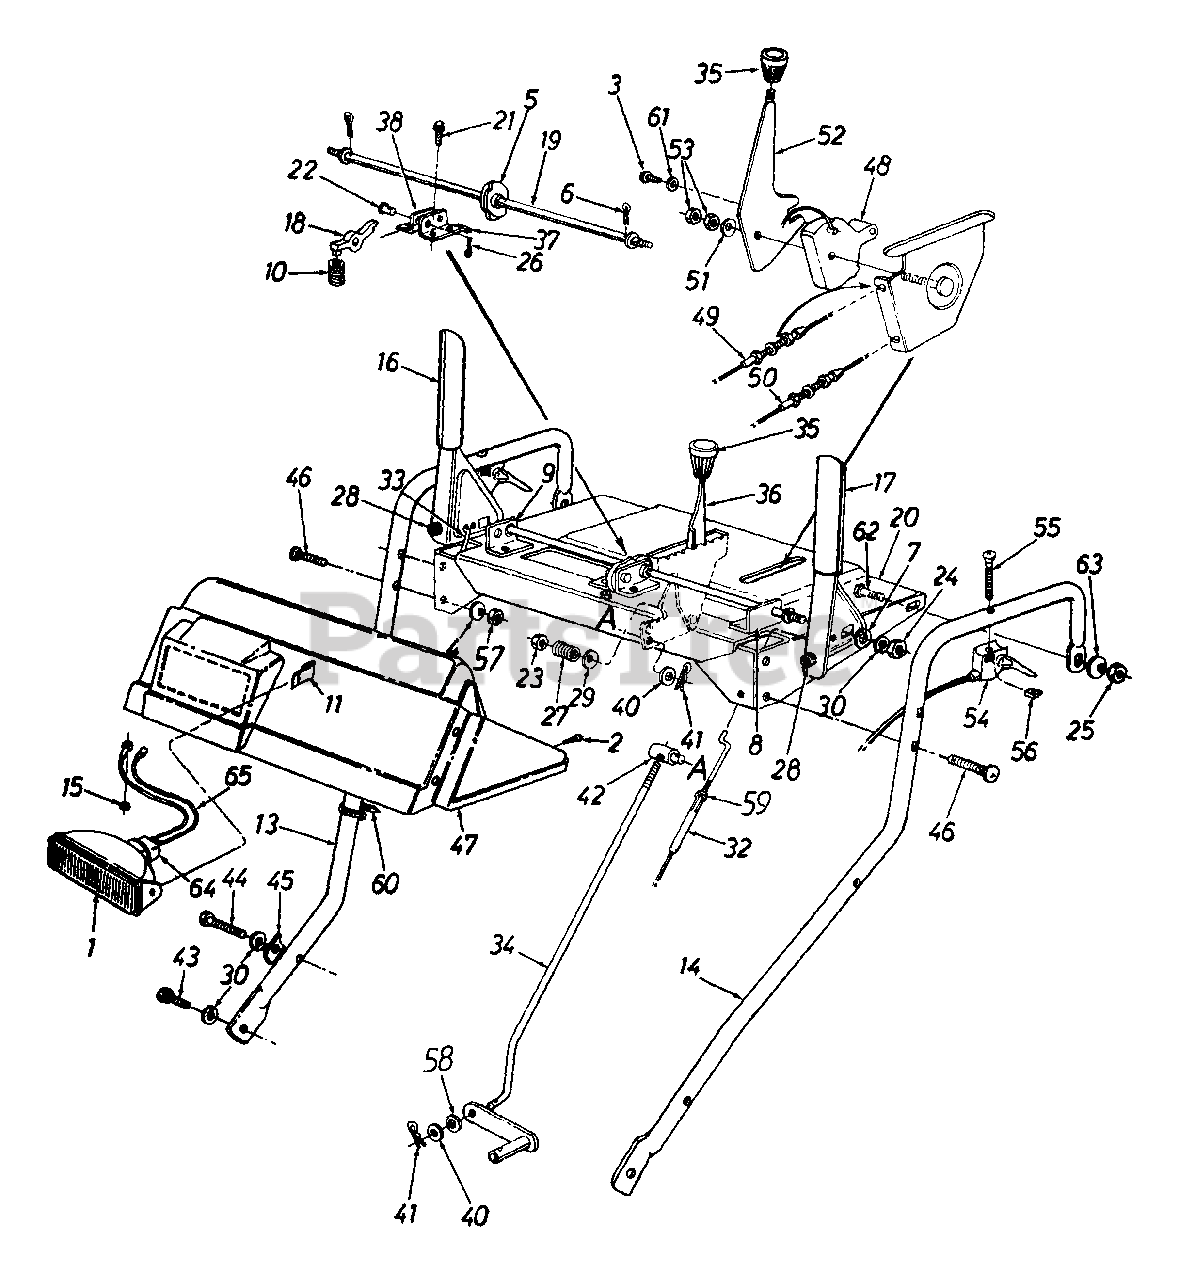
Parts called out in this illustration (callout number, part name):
1	Lamp Housing w/Lens (756G)
1	Bulb GE 892
2	Truss Mach. B-Tap Scr. #10 x .5
3	Hex AB-Tap Scr. 1/4 x .62" Lg.
4	Bell-Wash. .325" I.D. x .88" O.D.
5	Cam Handle Lock
6	Cotter Pin 3/32" Dia. x .75" Lg.
7	Washer (Special) .72" O.D.
9	Handle Support Brkt. - R.H.
10	Compression Spring
11	Retaining Clip (7566)
13	Handle - R.H.
14	Handle - L.H.
15	Hex Sems Nut 1/4-20 Thd. (756G)
16	Engagement Handle - R.H.
17	Engagement Handle - L.H.
18	Pawl Handle Lock
19	Rod Cam
22	Clevis Pin .437" Dia. x .65" Lg.
23	Hex Ins. L-Nut 3/8-24 Thd.
24	Hex Nut 5/16-18 Thd.
25	Hex Nut 1/4-20 Thd.
26	Cotter Pin 3/32" Dia. x 1" Lg.
27	Compression Spring
28	Rubber Bumper
29	Bell-Wash. .38" I.D. x .88" O.D.
30	L-Wash. 5/16" I.D.
32	Auger Clutch Cable
33	Drive Clutch Cable
34	Shift Rod
35	Shift Knob (756G)
36	Shift Handle
37	Handle Brkt. - L.H.
38	Handle Brkt. - R.H.
40	Fl-Wash. .344" I.D. x .62" O.D.
41	Internal Cotter Pin 5/16" Dia.
42	Ferrule
43	Hex Bolt 5/16-18 x .62" Lg. (Special)
44	Hex Bolt 5/16-18 x 1.75" Lg. (Gr. 5)
45	Handle Tab
46	Curved Carr. Bolt 5/16-18 x 1.5" Lg.
47	Handle Panel (756G)
47	Handle Panel (746E)
48	Cable Guide (756G)
49	Chute Control Cable (756G)
50	Chute Control Cable w/Clip (756G)
51	Bell-Wash. .325" I.D. x .93" O.D.
52	Chute Tilt Handle (7566)
53	Hex Cent. L-Nut 5/16-18 Thd.
54	Track Steer Cable w/Trigger
55	Oval C-Sunk Hd. Scr. 10-24 x 1.375" Lg.
56	Flat Weld Nut #10-24 Thd.
57	Hex Nut 5/16-18 Thd.
58	Spr. Wash. .32" I.D. x .62" O.D.
59	Hex Nut #10-24 Thd.
60	Cable Tie
61	Washer (Special) 1.25" O.D. (756G)
62	Hex Bolt 1/4-20 x .85" Lg.
63	Bell-Wash. .265" I.D. x .75" O.D.
65	Wire Harness (756G)
